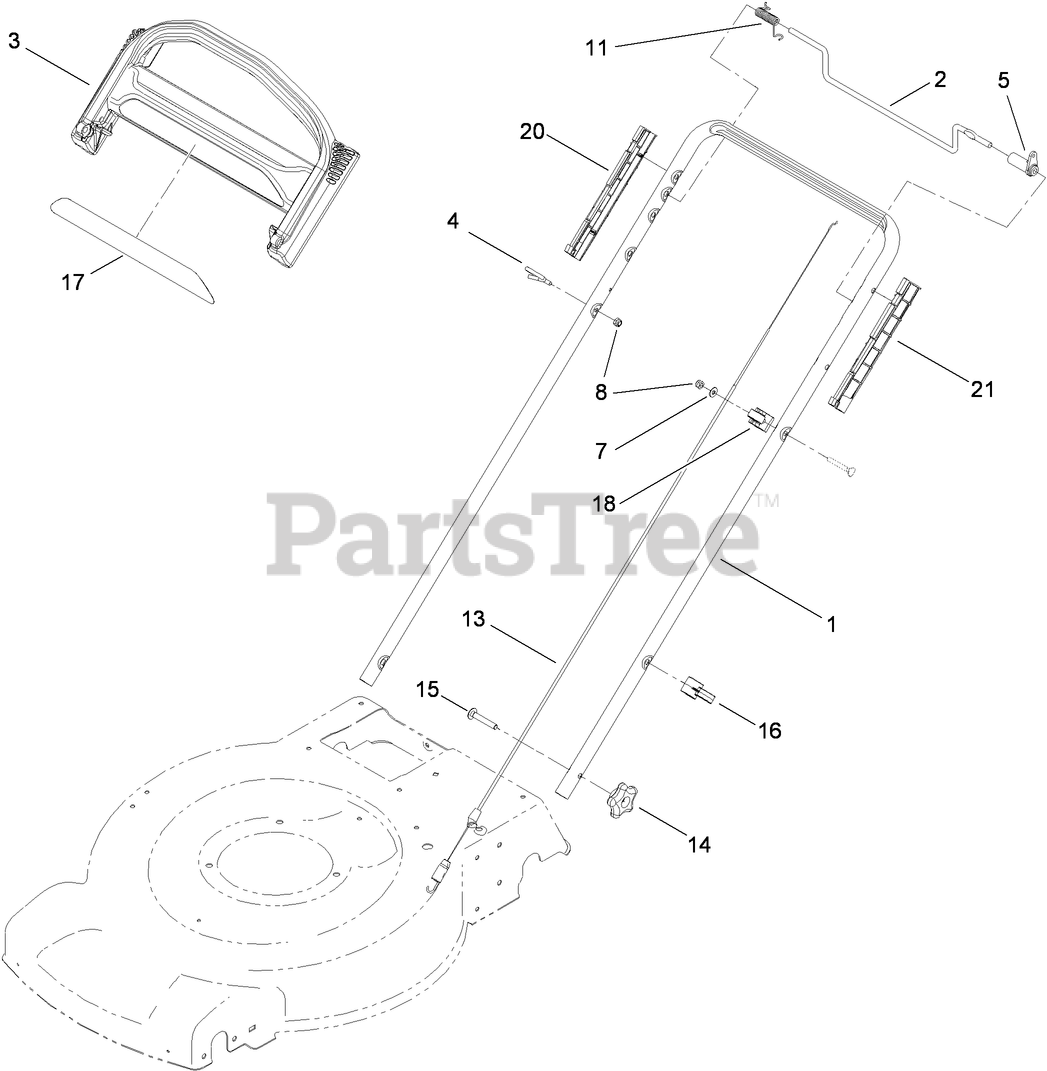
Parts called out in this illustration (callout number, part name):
3	HANDLE-CONTROL
4	GUIDE-ROPE
5	LEVER-TRACTION
7	WASHER-FLAT
8	NUT-LOCK, NI
13	CABLE-TRACTION
14	KNOB-HANDLE
15	BOLT-CARR
17	DECAL-HANDLE
20	GUIDE-RH
21	GUIDE-LH
